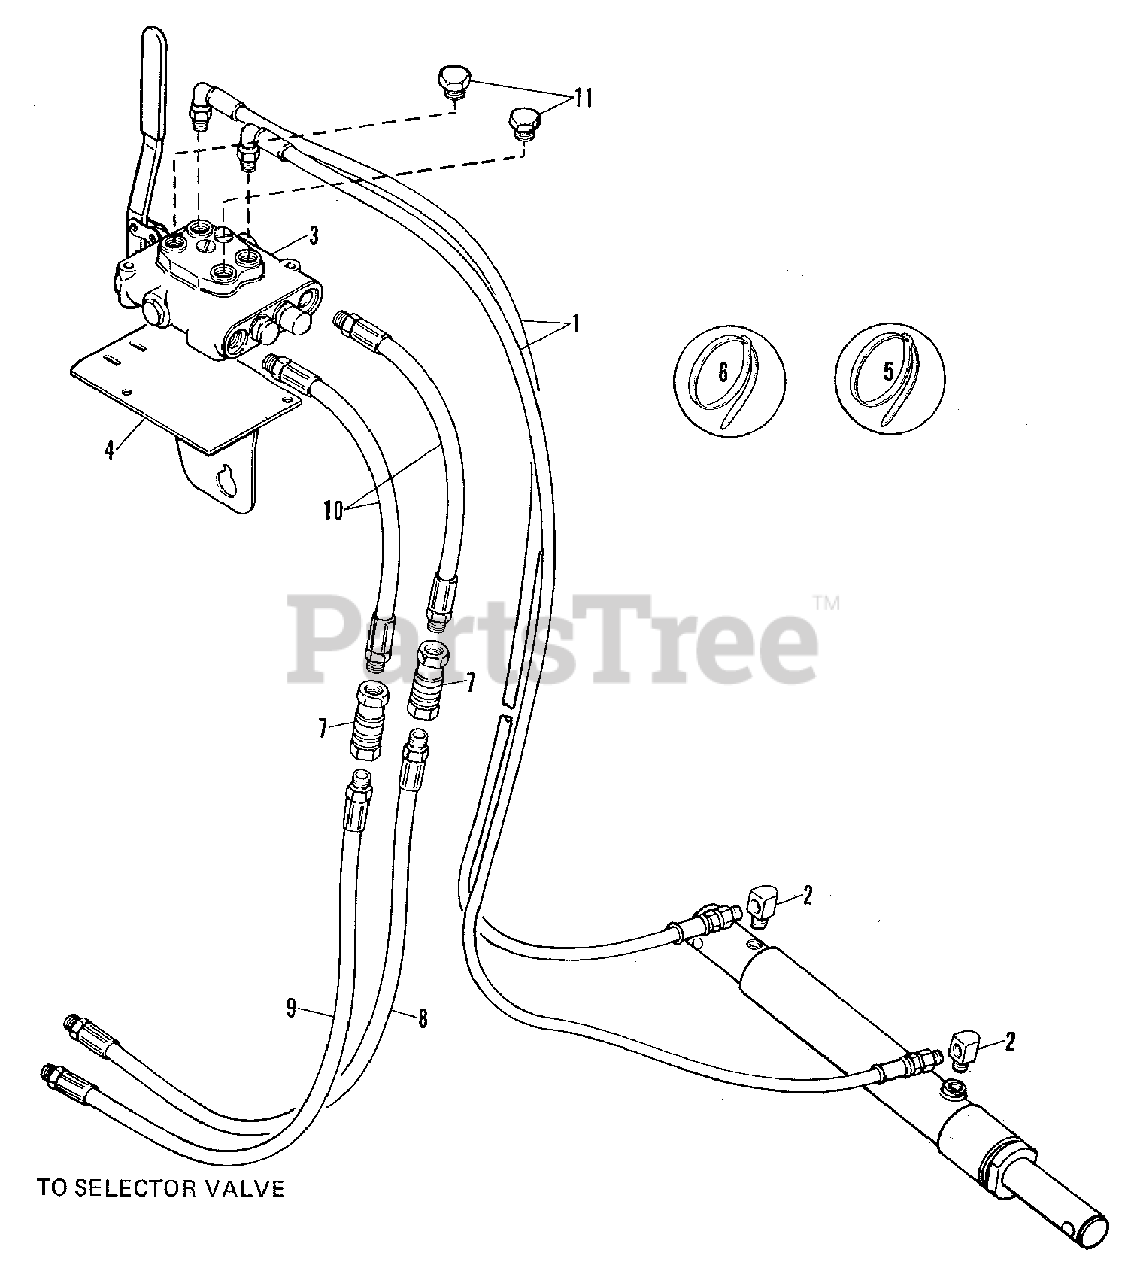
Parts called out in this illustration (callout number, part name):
1	HOSE ASSEMBLY, 102" Long (Cylinder to Cotnrol Valve)
2	ELBOW, Street, 90 Degrees, 1/4NC
3	VALVE, Control
3	CAPSCREW, 1/4NC x 2
3	LOCKWASHER, 1/4
4	BRACKET, Valve Mounting
4	CAPSCREW, 8MM x 25MM
4	LOCKWASHER, 5/16
4	WASHER, Plain, 5/16 x 3/4 x 16 Ga.
5	TIE, Plastic (To Tie 2 Hoses Together)
6	TIE, Plastic (To Tie 2 Hoses to Tractor)
7	COUPLER, Hose
8	HOSE ASSEMBLY (Selector Valve to Control)
9	HOSE ASSEMBLY (Control to Manifold)
10	HOSE ASSEMBLY (Valve Inlet & Outlet)
11	PLUG, Straight Thread, 9/16NC (w/O-Ring)
